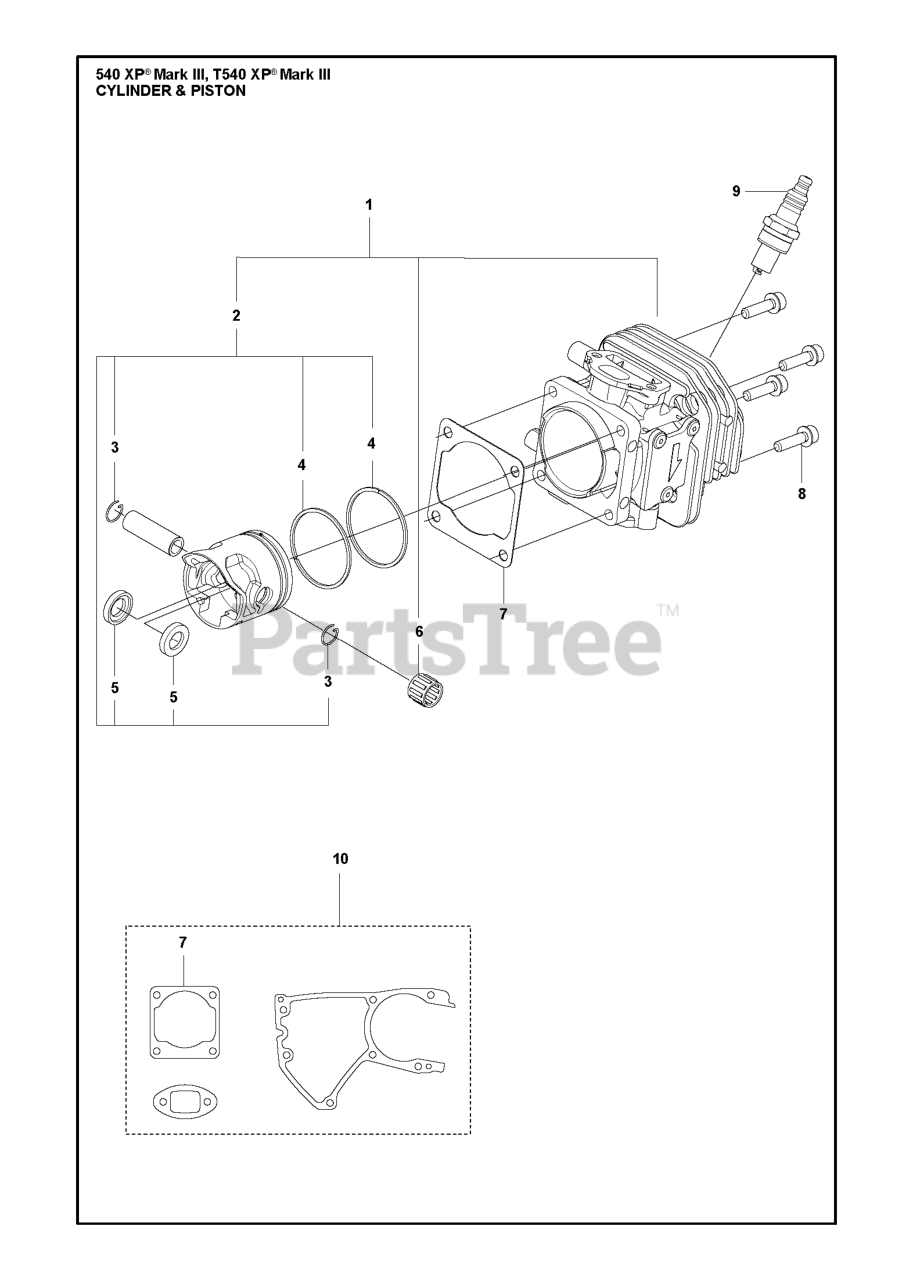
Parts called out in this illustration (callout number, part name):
3	LOCKING RING
6	NEEDLE BEARING
8	SCREW HEXABOULAR SLOTTED SOCKE
9	CMR6H SPARK PLUG NGK
